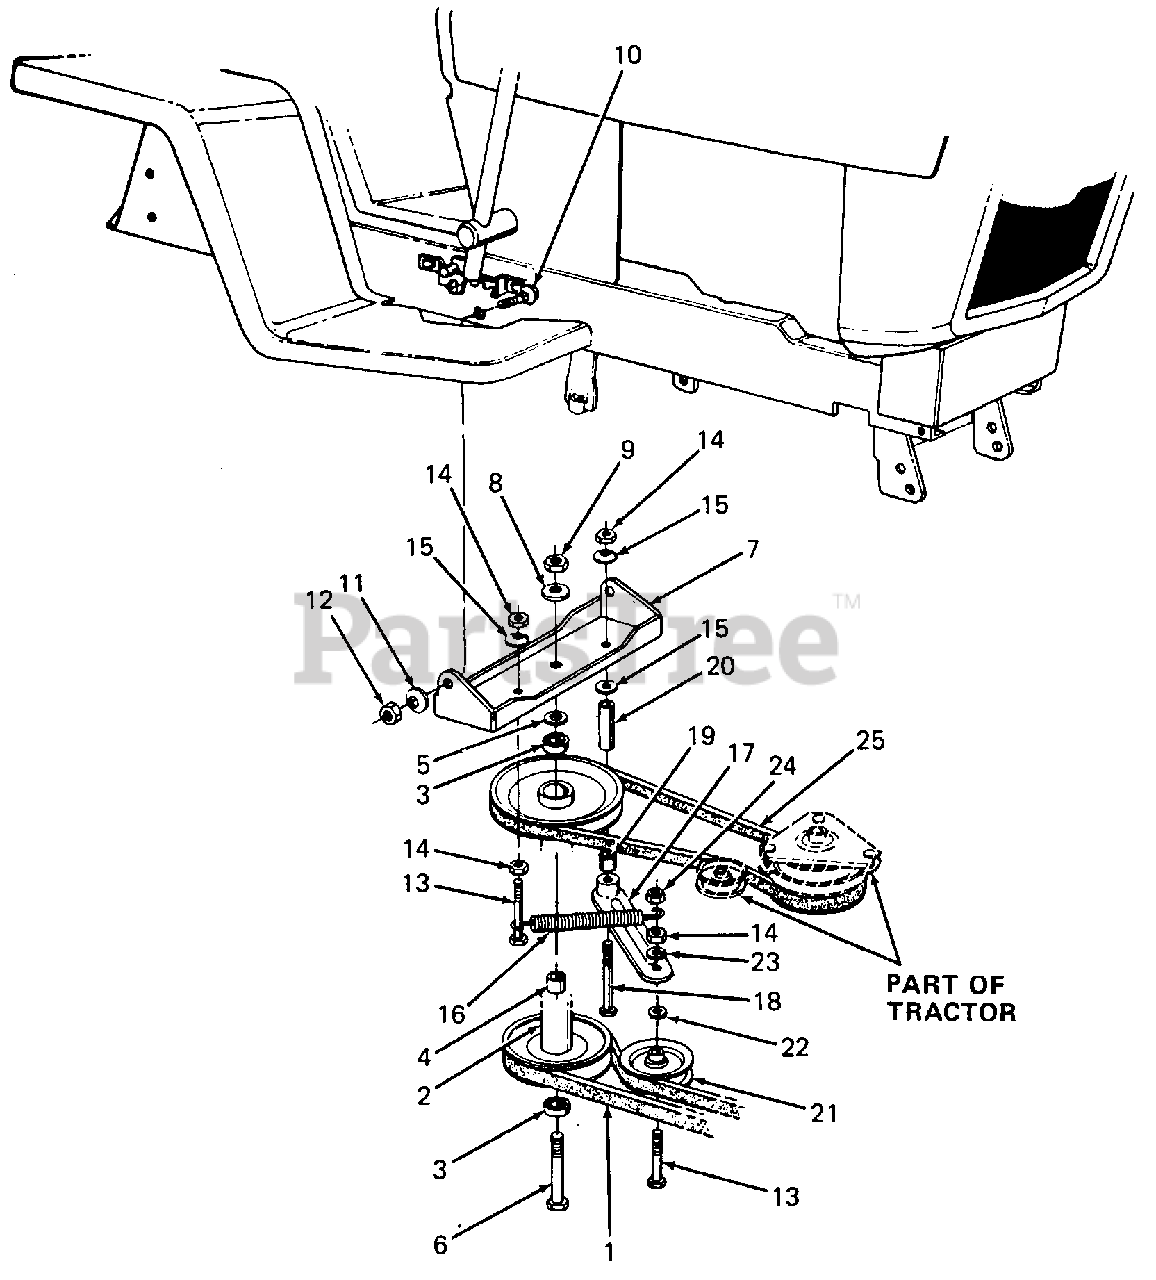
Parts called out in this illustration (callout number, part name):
1	V-Belt, 1/2 X 90.0 Lg
2	Pulley Assembly, Double Drive
3	Bearing, Ball, .62 X 1.38 X .44 Wide
4	Spacer, Pulley
5	Washer, Flat, .640 X 1.0 X .063 Thk HDN
6	Screw, Hex Cap, 5/8-18 X 5.0 Lg GR5
9	Nut, Hex Jam, 5/8-18
10	Bolt, Carriage, 5/16-18 X .62 Lg
11	Washer, Bell, .345 X .88 X .060 Thk
12	Nut, Hex, 5/16-18
13	Screw, Hex Cap, 3/8-16 X 2.25 Lg
14	Nut, Hex Jam, 3/8-16
15	Washer, Bell, .380 X .88 X .060 Thk
16	Spring, Extension, .53 OD X 4.75 Lg
17	Arm, Idler
18	Screw, Hex Cap, 3/8-16 X 3.25 Lg
19	Spacer, .3776 X .500 X .830 Lg
20	Spacer, .37 X .562 X 1.50 Lg
21	Pulley, Idler
22	Washer, Flat, .378 X 1.0 X .125 Thk
23	Washer, Lock, 3/8
24	Nut, Hex Center Lock Jam, 3/8-16
25	V-Belt, 1/2 A X 48.0 Lg
